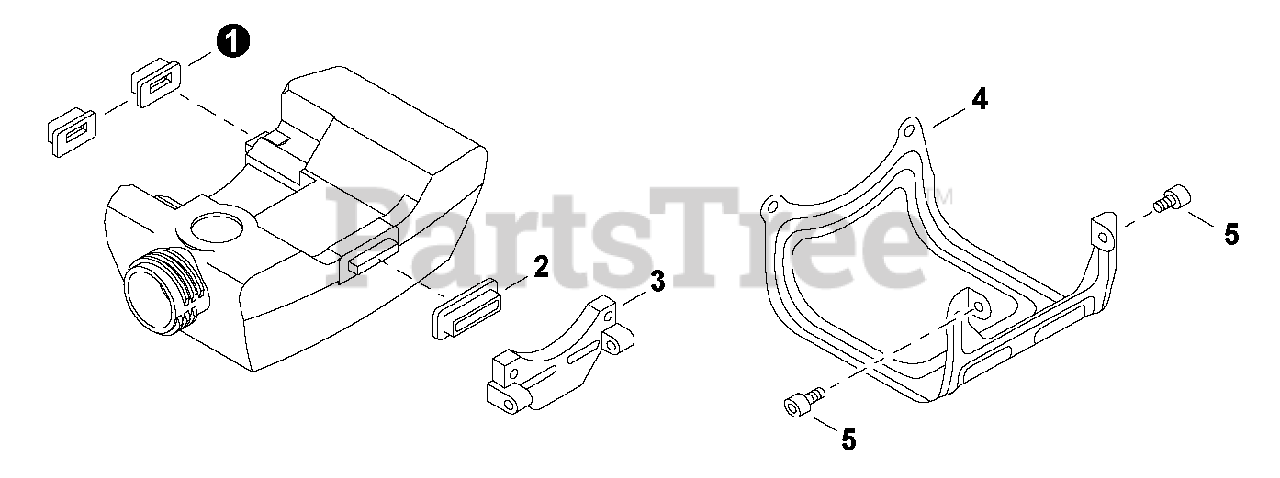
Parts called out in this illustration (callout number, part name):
1	CUSHION, FUEL TANK
2	CUSHION, FUEL TANK - REAR
3	BRACKET, FUEL TANK
4	TANK GUARD ASSY - PLASTIC
5	BOLT M5×12
